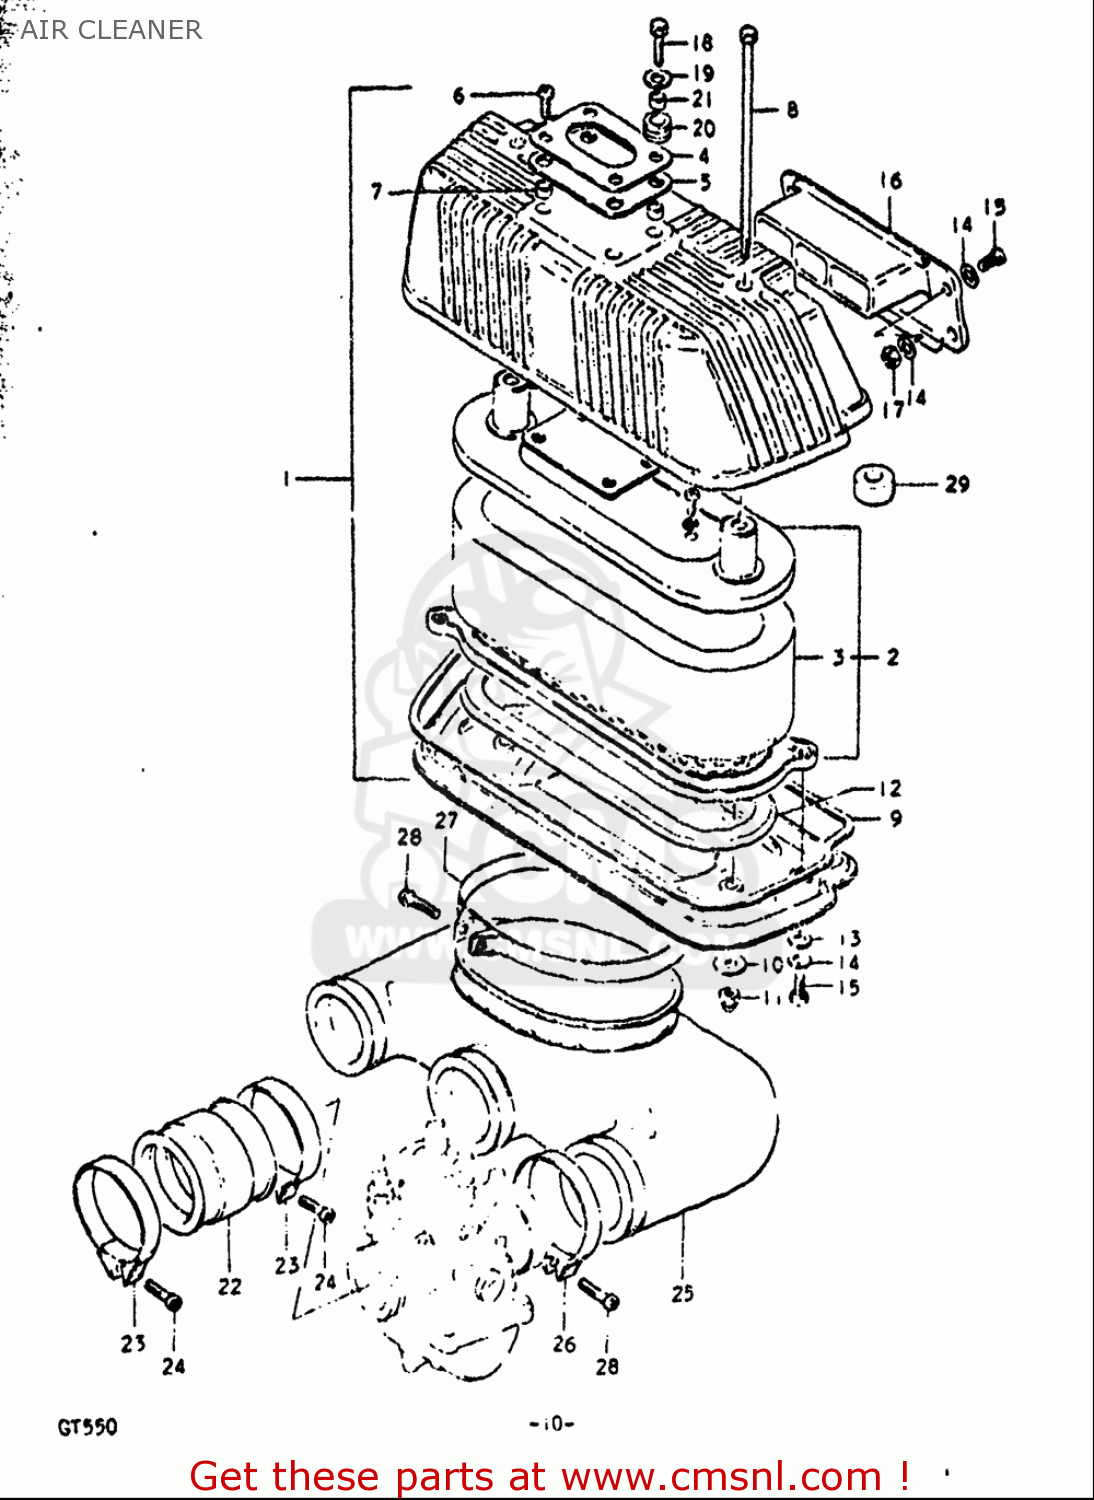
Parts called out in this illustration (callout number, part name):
3	FILTER
6	SCREW
11	NUT
14	WASHER
15	SCREW
17	NUT
18	BOLT
19	WASHER(6.5X20X1.2)
20	CUSHION
21	SPACER,6.5X9X7
22	PIPE,INTAKE
23	CLAMP
24	SCREW
26	CLAMP
27	CLAMP
28	SCREW
